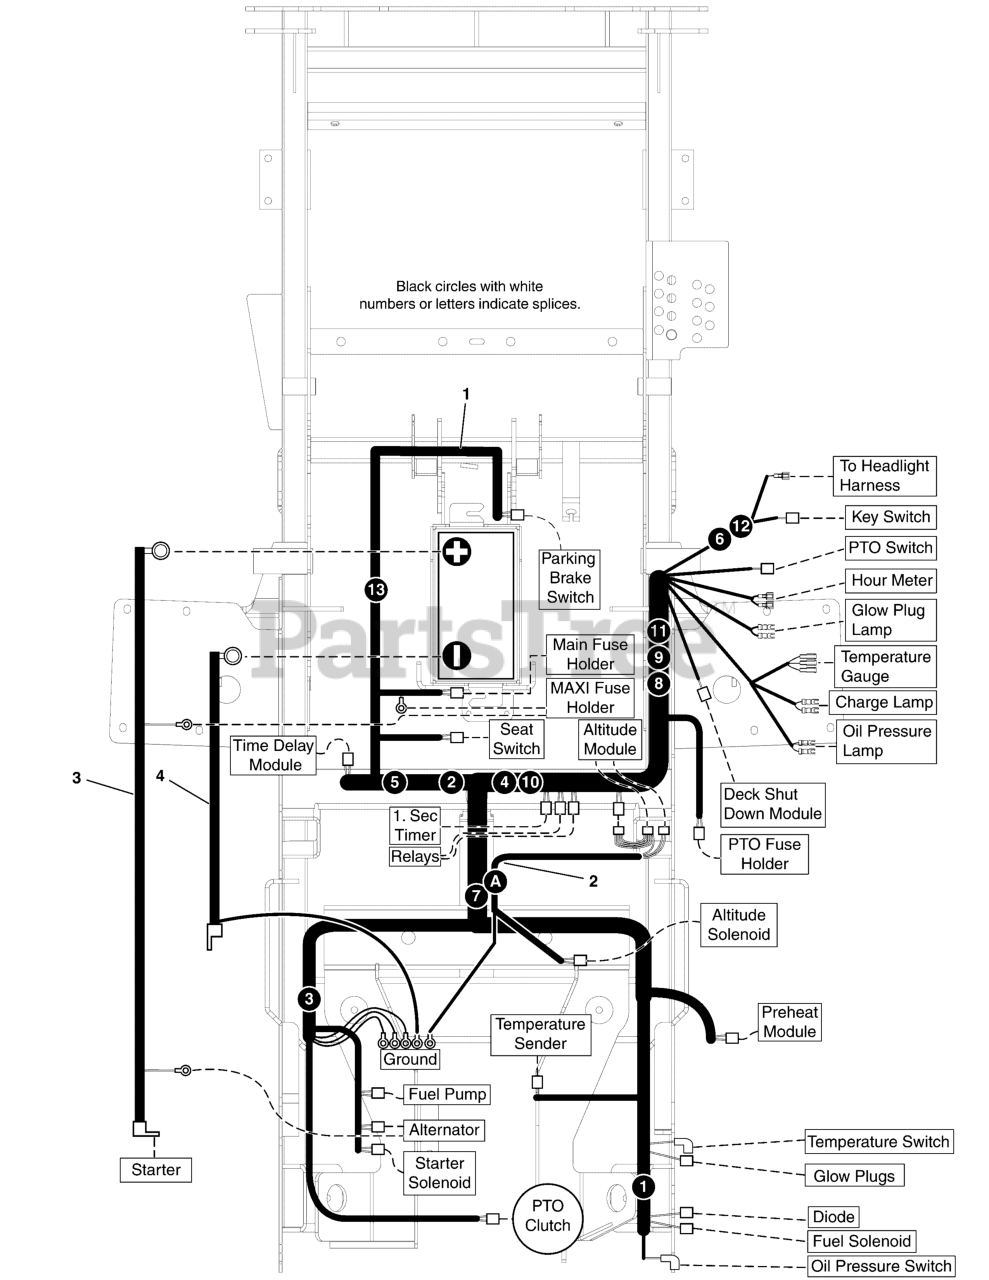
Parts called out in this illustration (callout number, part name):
1	WIRE HARNESS, MAIN, IS2600
2	WIRE HARNESS, ALTITUDE/SOLENOID, IS2600
3	ASSEMBLY, POS BATTERY CABLE, IS2600
4	BATTERY CABLE, NEG
